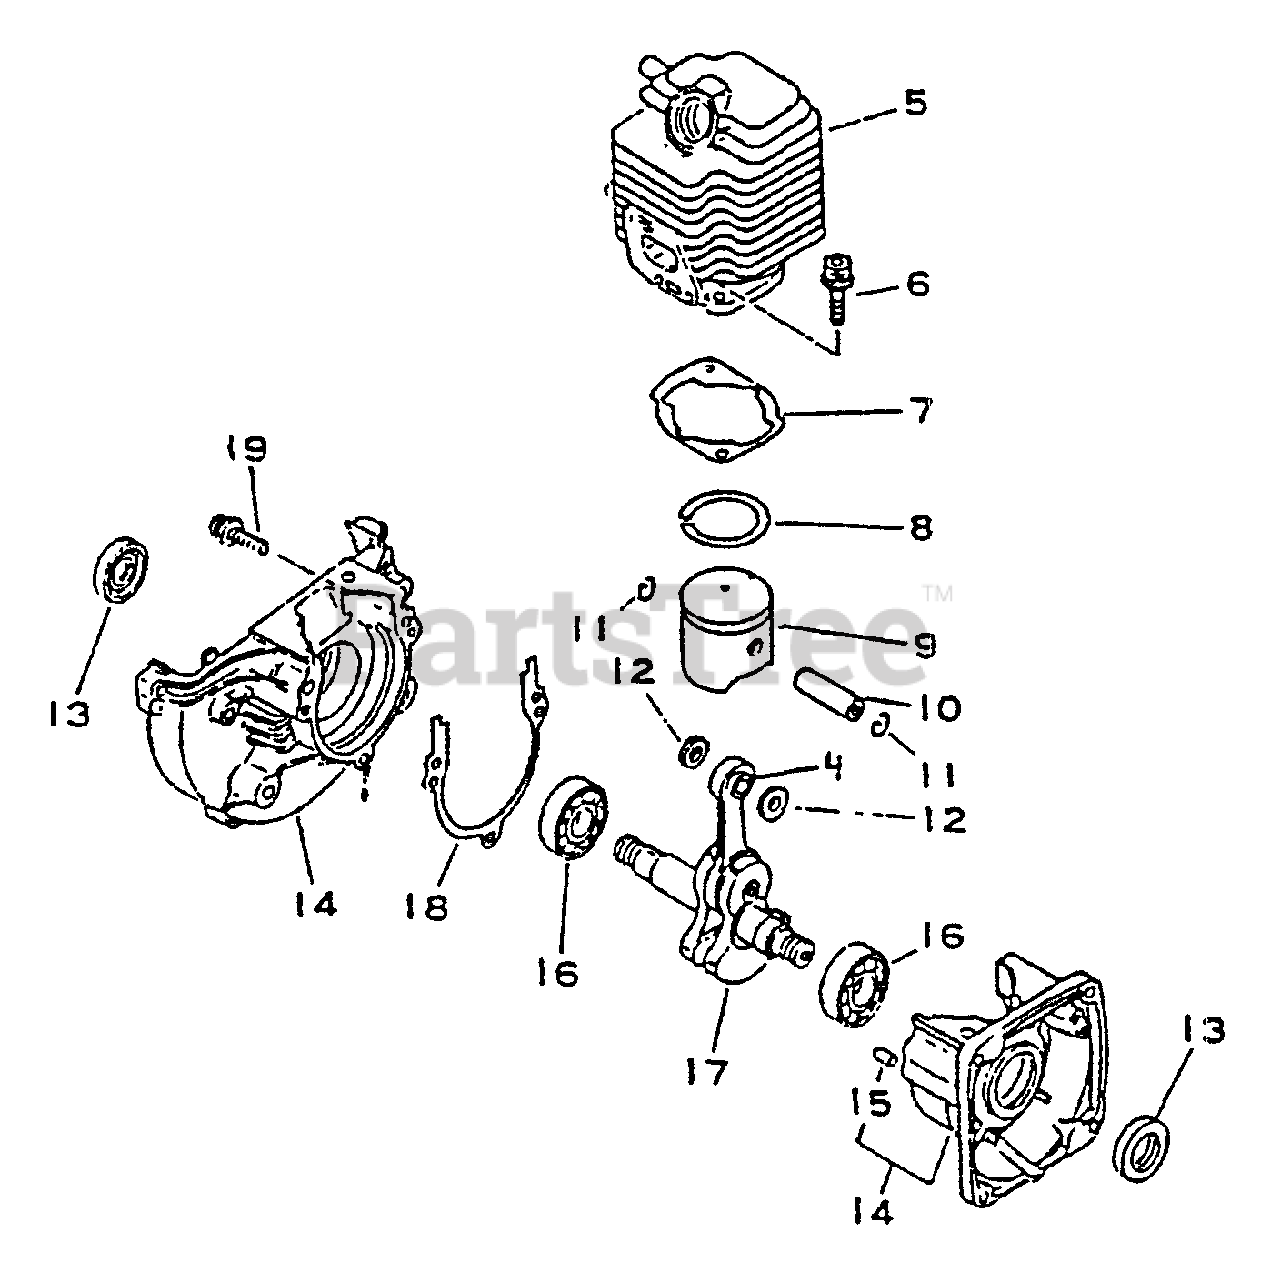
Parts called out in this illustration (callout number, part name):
4	BEARING, NEEDLE
6	BOLT 5×22
7	GASKET, CYLINDER
8	RING, PISTON
9	PISTON
10	PIN, PISTON 8
11	RING, SNAP
12	WASHER, THRUST
13	SEAL, OIL 12
14	CRANKCASE KIT
15	PIN, LOCATING 4
16	BEARING, BALL - 6201 C3
17	CRANKSHAFT ASSY
18	GASKET, CRANKCASE
19	SCREW 5×28
